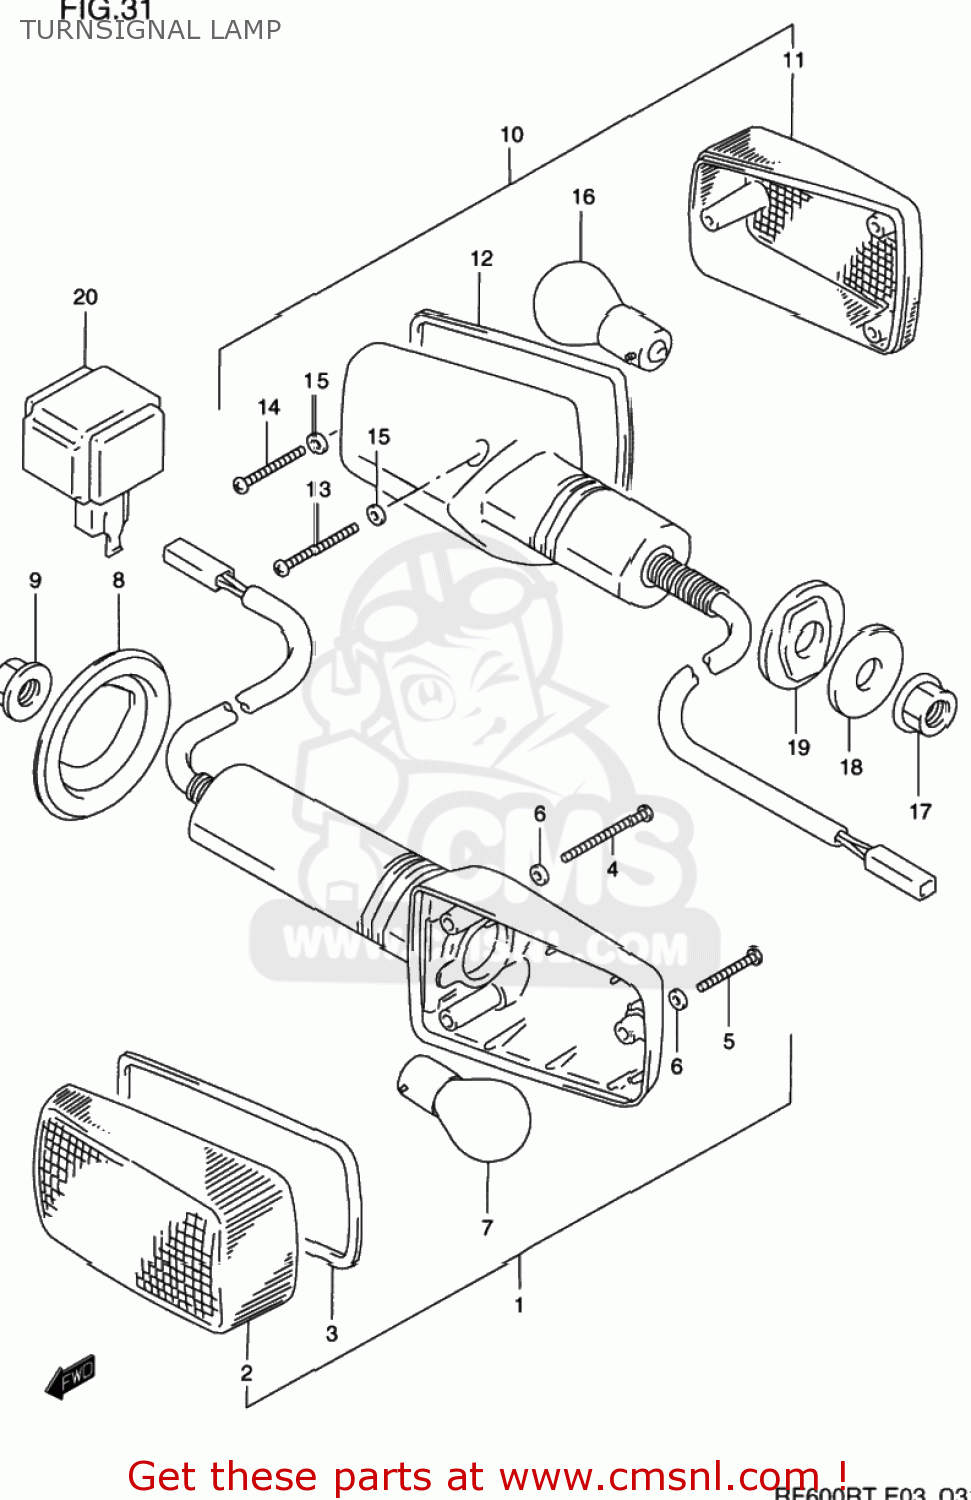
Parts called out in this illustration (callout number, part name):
1	LAMP ASSY,FR TURN SIGNAL
2	LENS
3	GASKET (NAS)
4	SCREW(3X30)
5	SCREW
6	GASKET (NAS)
7	BULB(12V21W)
8	GROMMET
9	NUT
10	LAMP ASSY,RR TURNSIGNAL
11	LENS
12	GASKET (NAS)
13	SCREW(3X30)
14	SCREW
15	GASKET (NAS)
16	BULB(12V21W)
17	NUT
18	WASHER(10.5X30X3.2)
19	SPACER,RR TURNSIGNAL
20	RELAY ASSY,TURNSIGNAL LAMP
